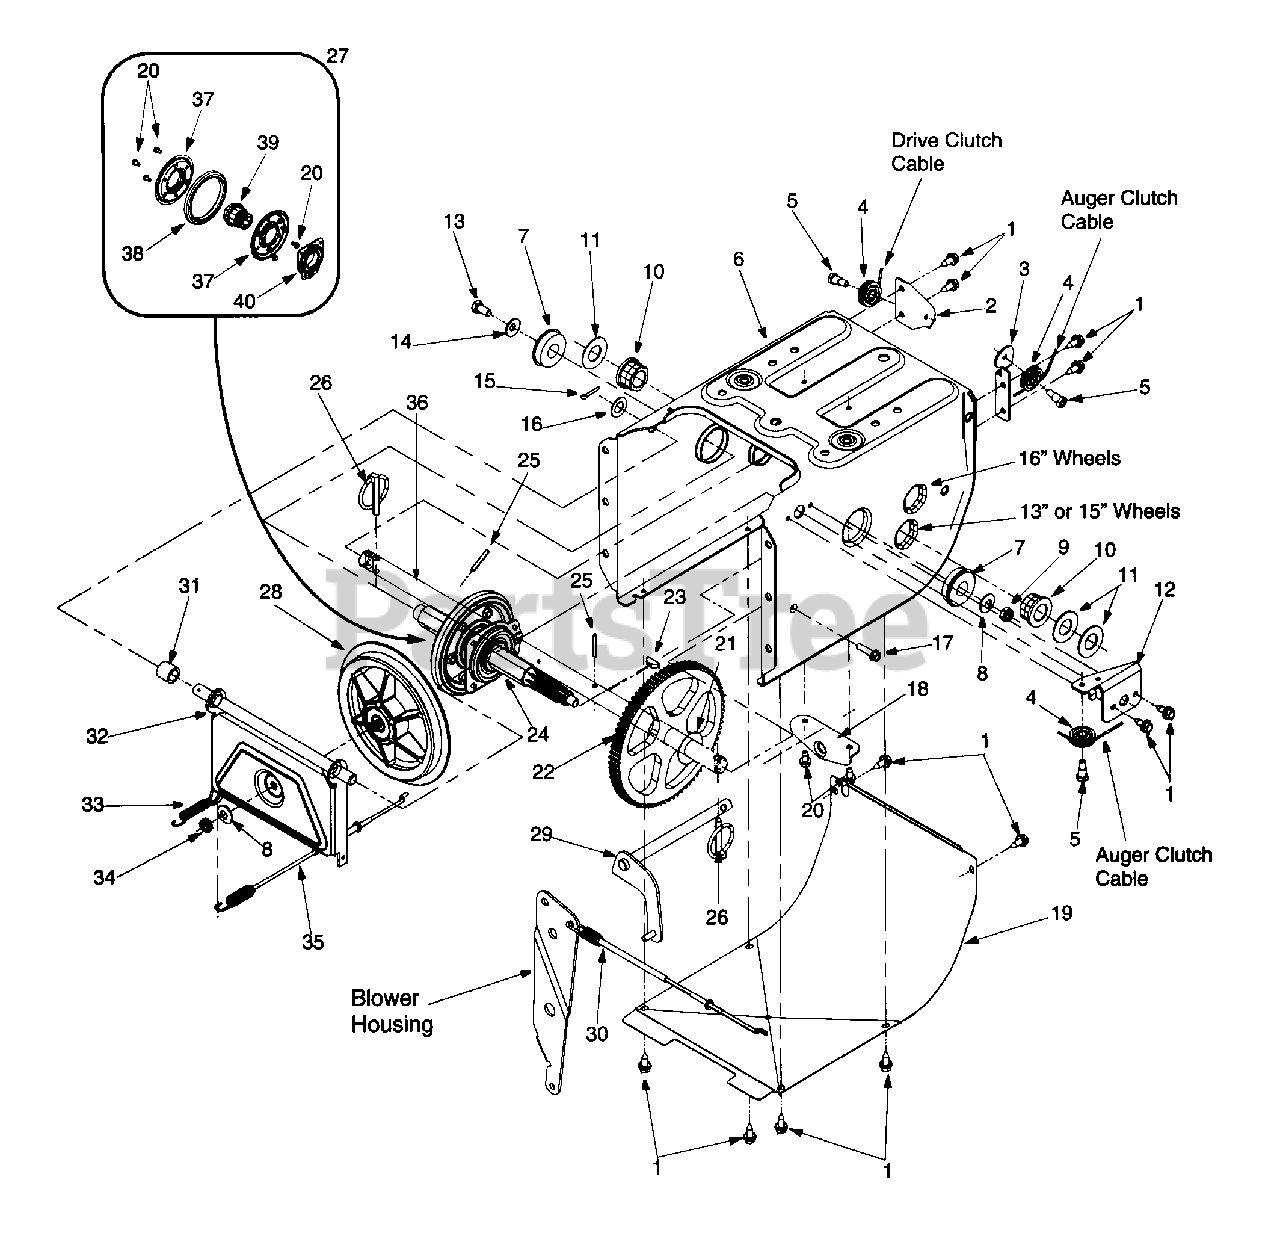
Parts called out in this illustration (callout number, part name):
1	Hex Screw
2	Drive Cable Guide Bracket
3	Auger Clutch Cable Bracket
4	Roller Cable
5	Hex Screw 1/4-28
8	Bell Washer
9	Lock Jam Nut
10	Hex Flange Bearing
11	Flat Washer
12	Front Support Guide Bracket
13	Lock Hex Screw
14	Bell Washer .340 ID x .872 OD
15	Cotter Pin
16	Flat Washer .536 ID x .930 OD
17	Hex Washer Screw 1/4-20
21	Flat Washer .760 ID x .50 OD
23	Key
24	7-Tooth Shaft
25	Roll Pin
26	Klik Pin
27	Friction Wheel Assembly
28	Friction Disc Wheel
29	Wheel Shift Rod Assembly
30	Drive Cable
31	Spacer
32	Friction Wheel Bracket Assembly
33	Extension Spring
34	Jam Nut 3/8-24
35	Drive Cable
36	Axle 13" Wheels
36	Axle 16" Wheels
37	Friction Plate
38	Friction Wheel Rubber
39	Friction Wheel Hub
40	Friction Wheel Bearing
